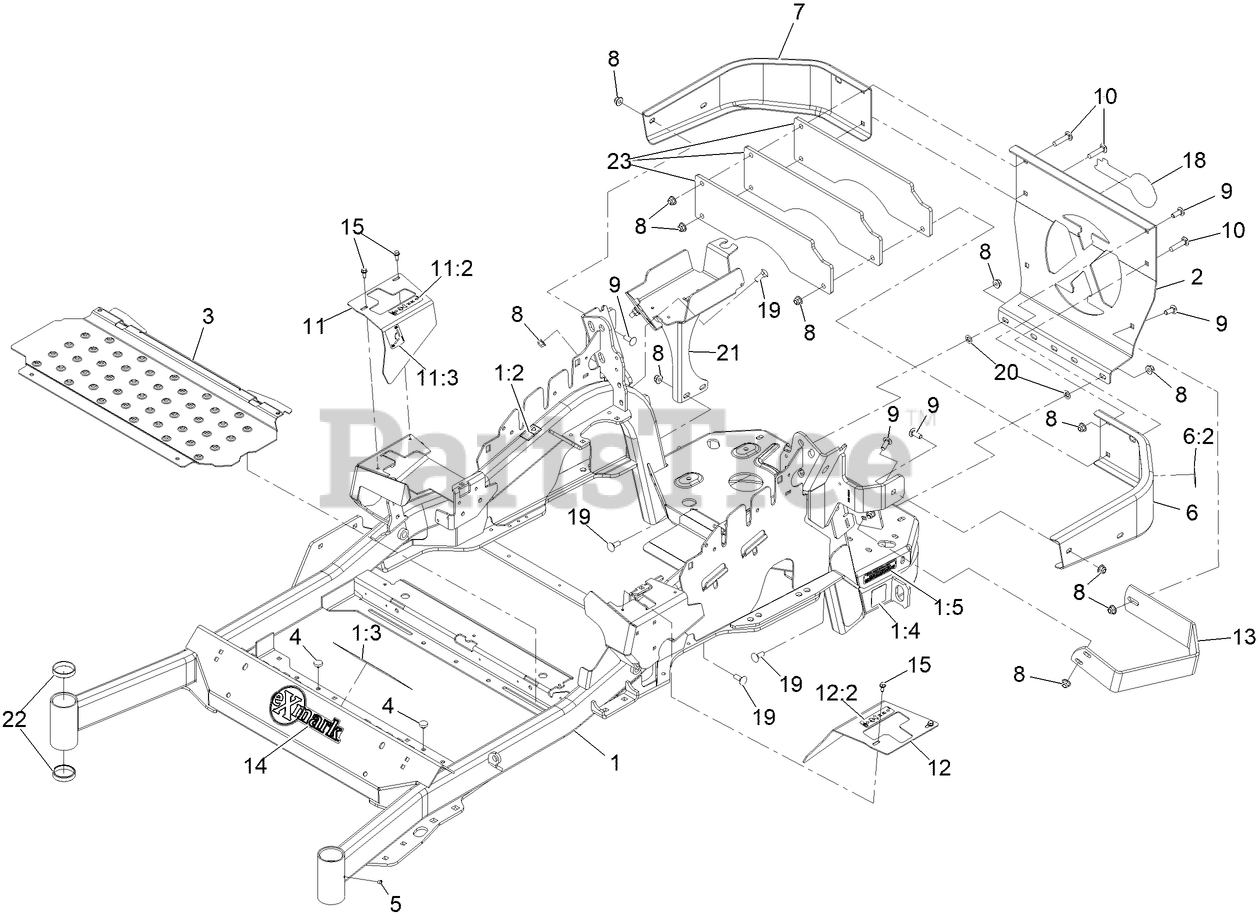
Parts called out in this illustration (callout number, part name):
1	Mainframe ASM-Rd W/Decals
1	Mainframe ASM- Rd W/Decals
1:2	DECAL-WARNING
1:3	DECAL-DANGER
1:4	DECAL-HAZARD, PINCHED FINGER
1:5	DECAL-ARRESTOR, SPARK
2	PLATE,REAR GUARD
6	LH BUMPER ASM
6:2	DECAL-WARNING
7	BUMPER-RH
8	NUT-HF, NI
9	SCREW-CARR
10	SCREW-CARR
11	RH MOTION CONTROL COVER ASM
11:2	DECAL-CONTROL, MOTION
11:3	DECAL-PARK BRAKE, CE
12	LH MOTION CONTROL COVER ASM
12:2	DECAL-CONTROL, MOTION
13	GUARD-MUFFLER
14	DECAL-EXMARK
15	SCREW-HWH
18	DECAL, EXMARK LOGO
19	BOLT-CARR
20	NUT-PUSH
21	Weld-Battery Mount
22	CUP-BEARING
23	PLATE-WEIGHT, 6 LB
